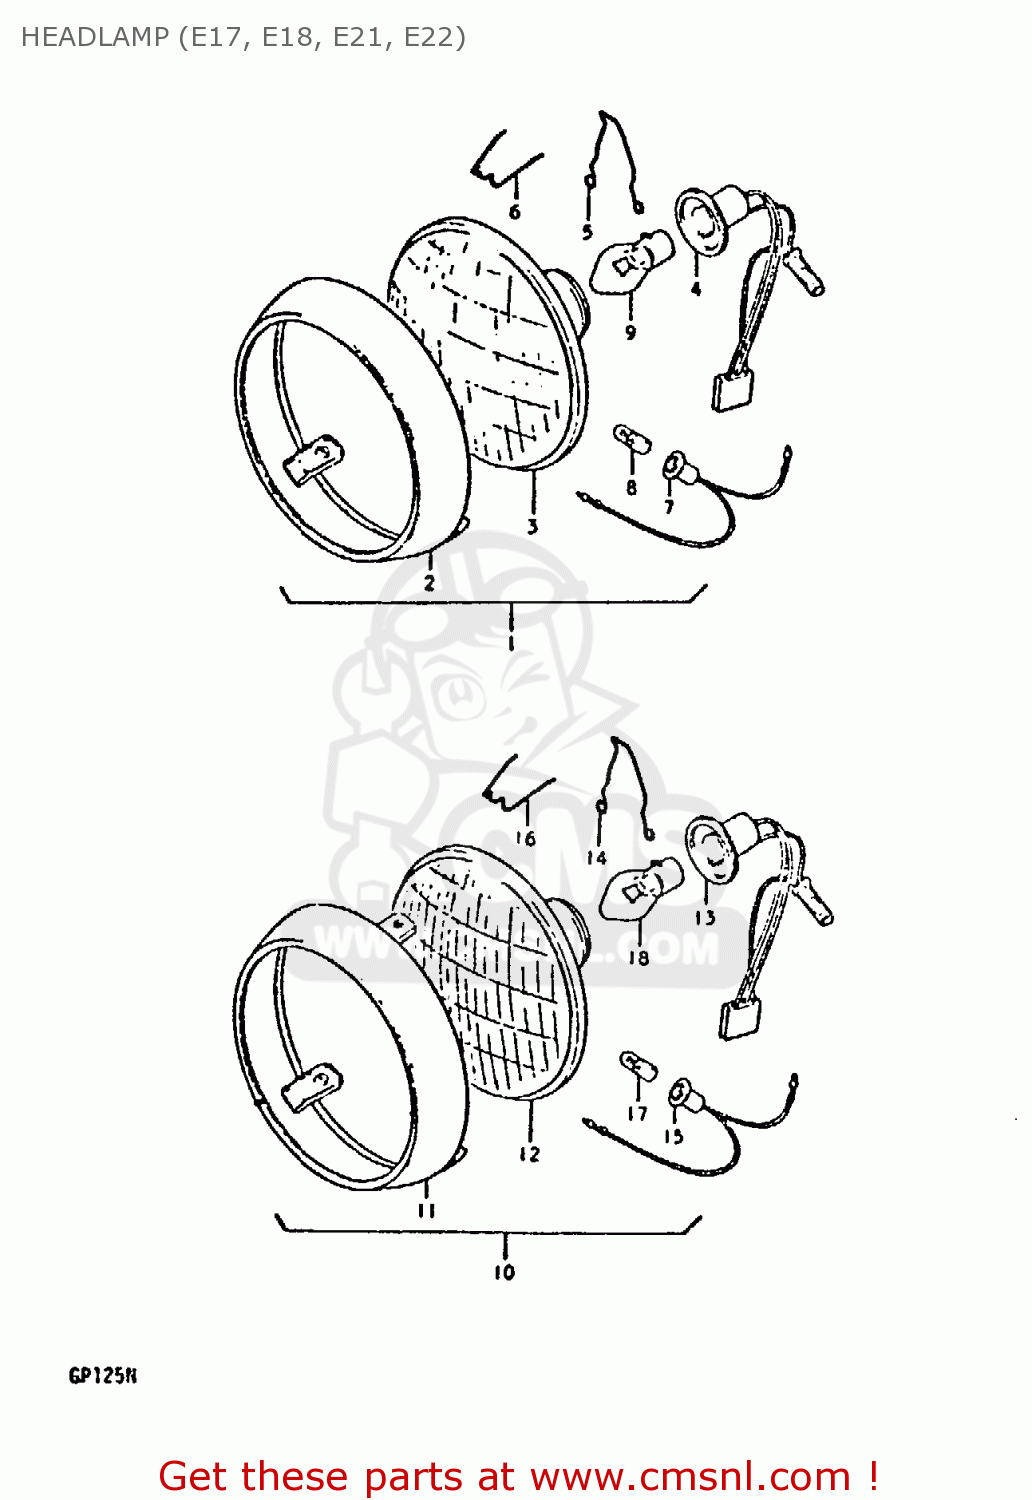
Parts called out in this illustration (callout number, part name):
1	HEADLAMP ASSY
2	RIM
3	UNIT
4	SOCKET
5	CLAMP,HEADLAMP
6	SPRING
7	SOCKET
8	BULB (6V,4W)
9	BULB (6V,25/25W)
